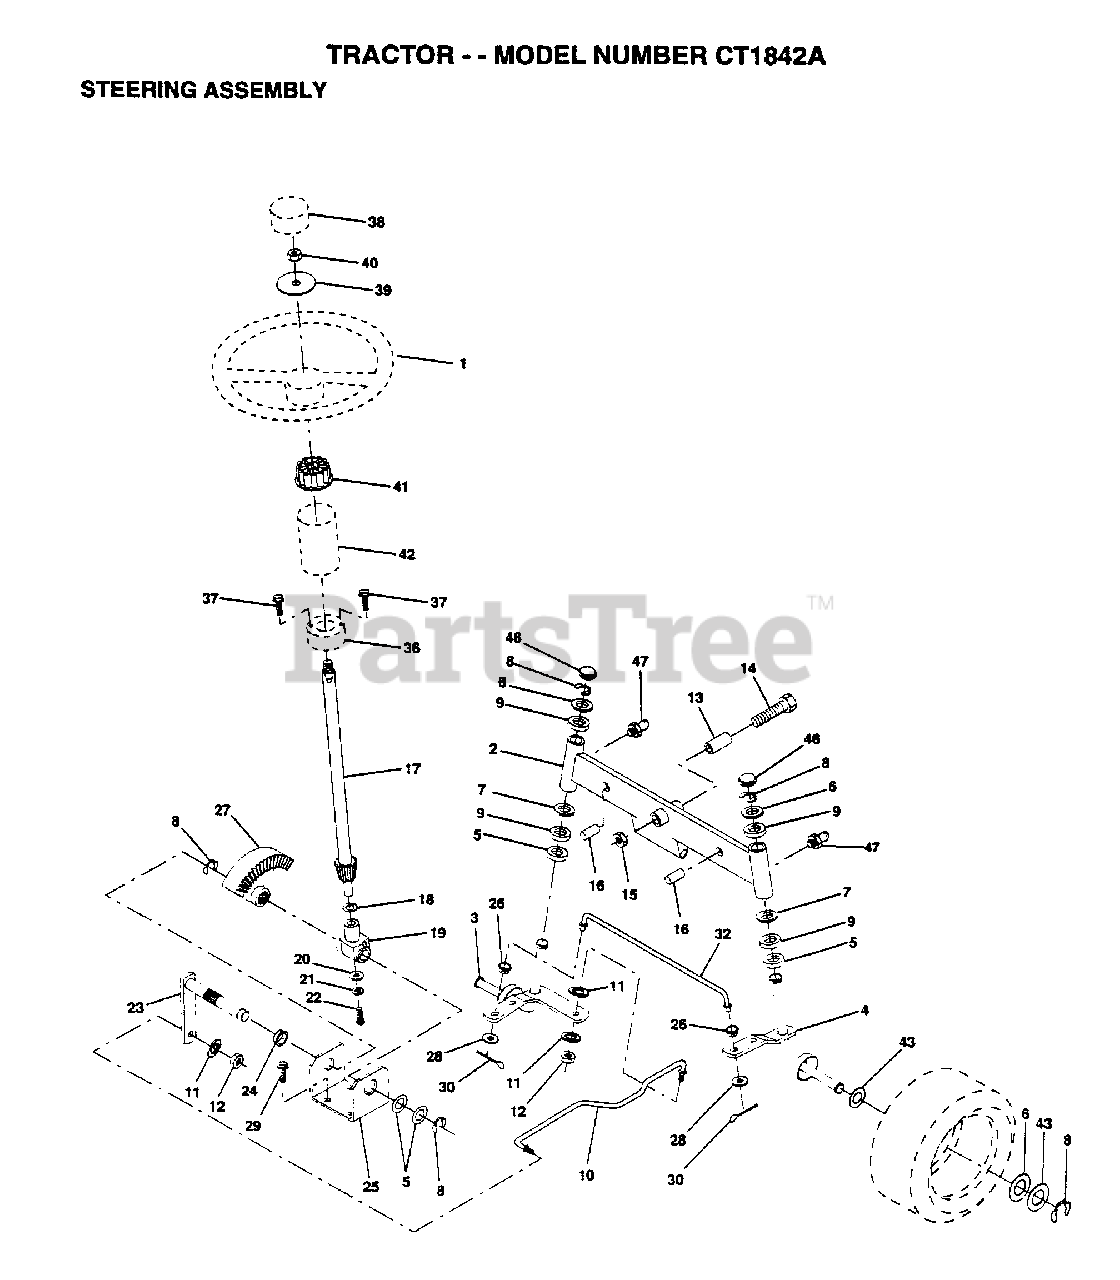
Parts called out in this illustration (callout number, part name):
1	WHEEL STR AYP BLK
2	AXLE ASM FRONT
3	SPINDLE LH
4	SPINDLE RH
5	WASHER .T
6	WASHER
7	WASHER
8	RING
9	COL. SRTG. BEAR.
11	LOCKWASHER
13	BEARING
14	BOLT HEX 5/8-11
15	"NUT-LOC,FLANGE LT"
16	AXLE PIN
17	SHAFT ASM
18	THRUST WASHER
19	SUPPORT.SHAFT
21	LOCKWASHER
22	"SCREW,SPECIAL"
24	NYLINER T
25	"BRKT,STEERING"
26	BUSHING.DRAGLINK
27	GEAR SECTOR
28	WASHER
29	SCREW
30	COTTER PIN
32	TIE ROD
38	CAP STEER AYP
39	WASHER T
40	GRIPCO NUT
41	ADAPTER-WHEEL LT
42	"TUBE, STR SHAFT"
43	WASHER
46	CAP
47	ZERK M
